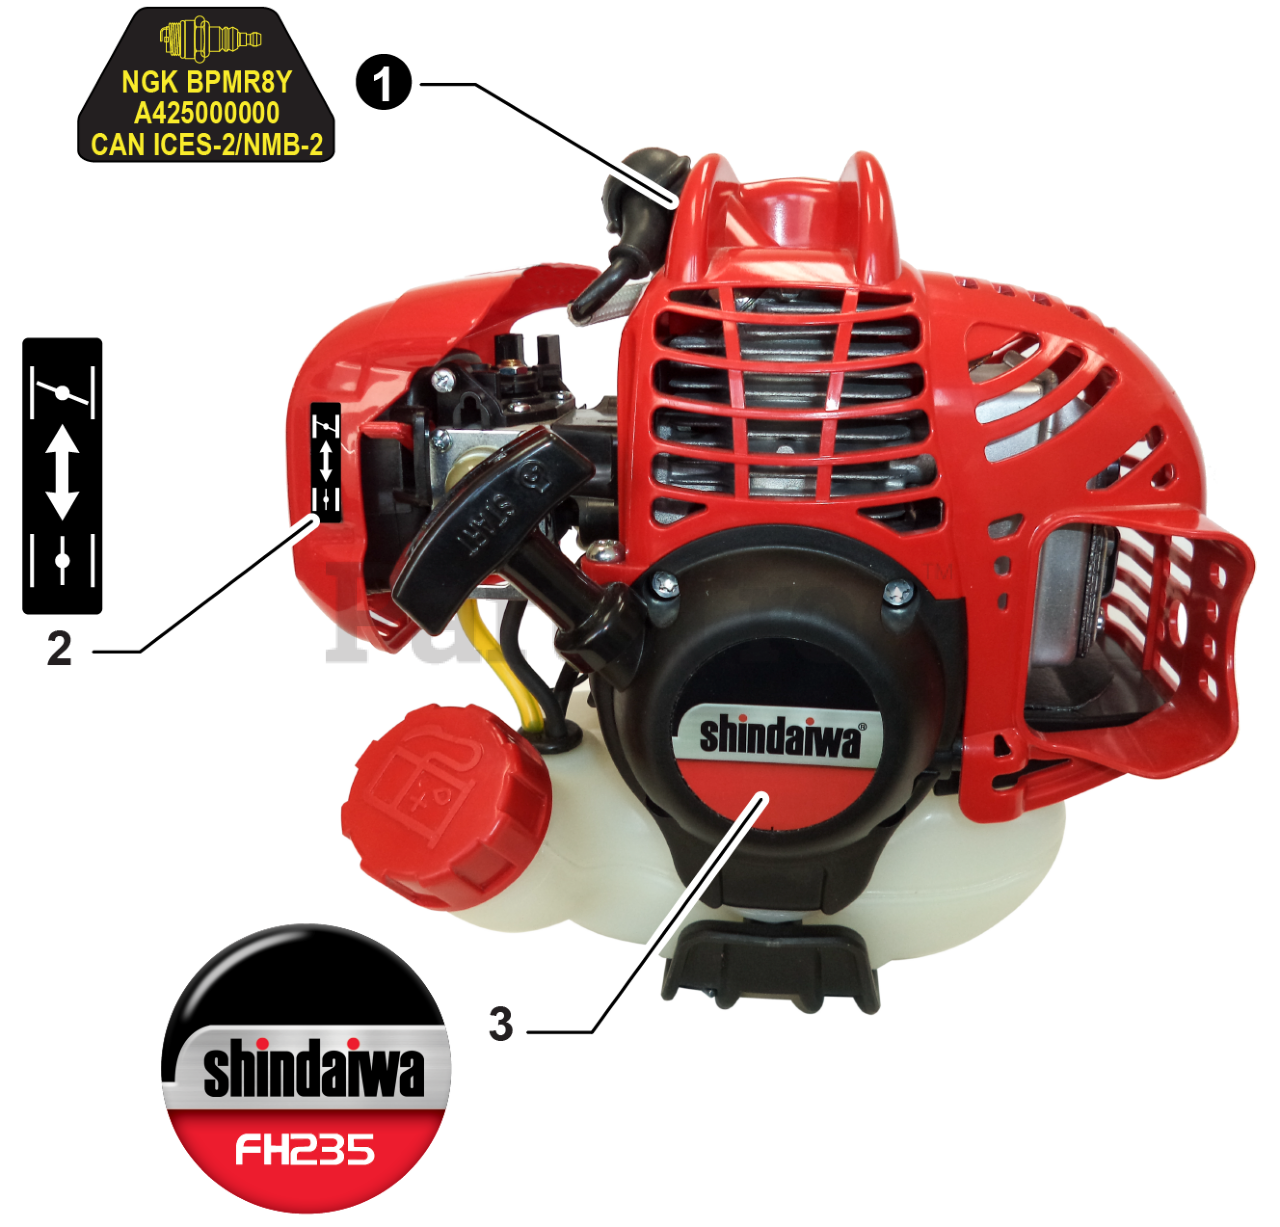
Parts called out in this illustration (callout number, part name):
1	LABEL - SPARK PLUG - BPMR8Y
2	LABEL - CHOKE
3	LABEL - SHINDAIWA - FH235
